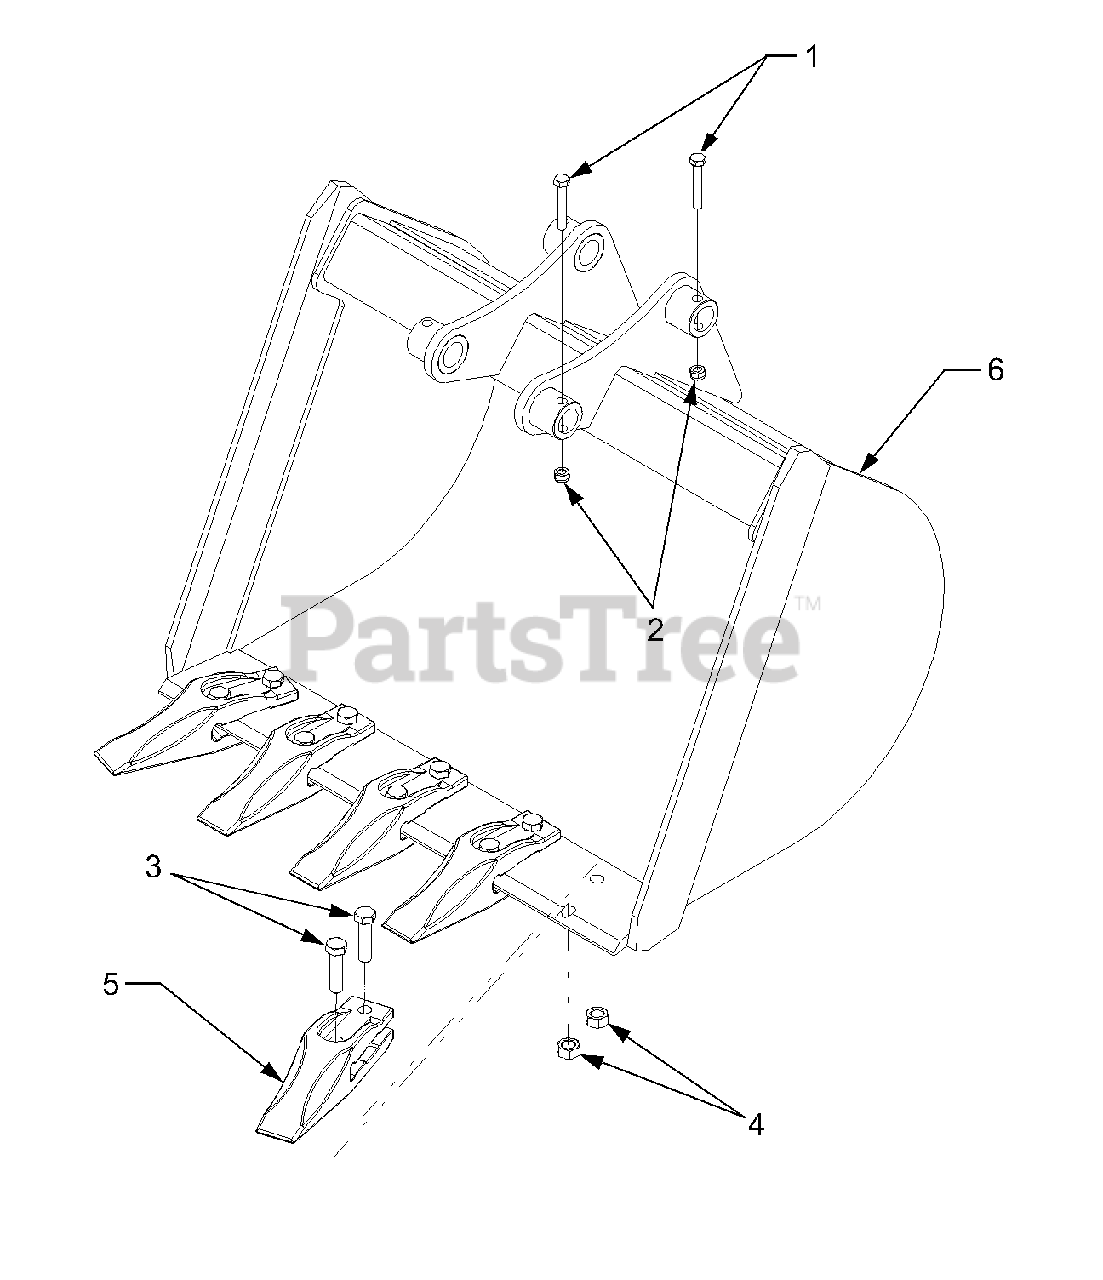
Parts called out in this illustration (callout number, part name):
1	Screw, Hex Cap, M8-1.25 x 50 Hardened
2	Nut, Hex Nylon Lock, M8-1.25
3	Screw,Hex Cap, M12-1.75 x 45 GR8.8 8" and 12" Bucket
4	Nut, Hex, M12-1.75 8" and 12" Bucket
5	Tine, Backhoe 8" and 12" Bucket
6	8" Bucket Assembly
